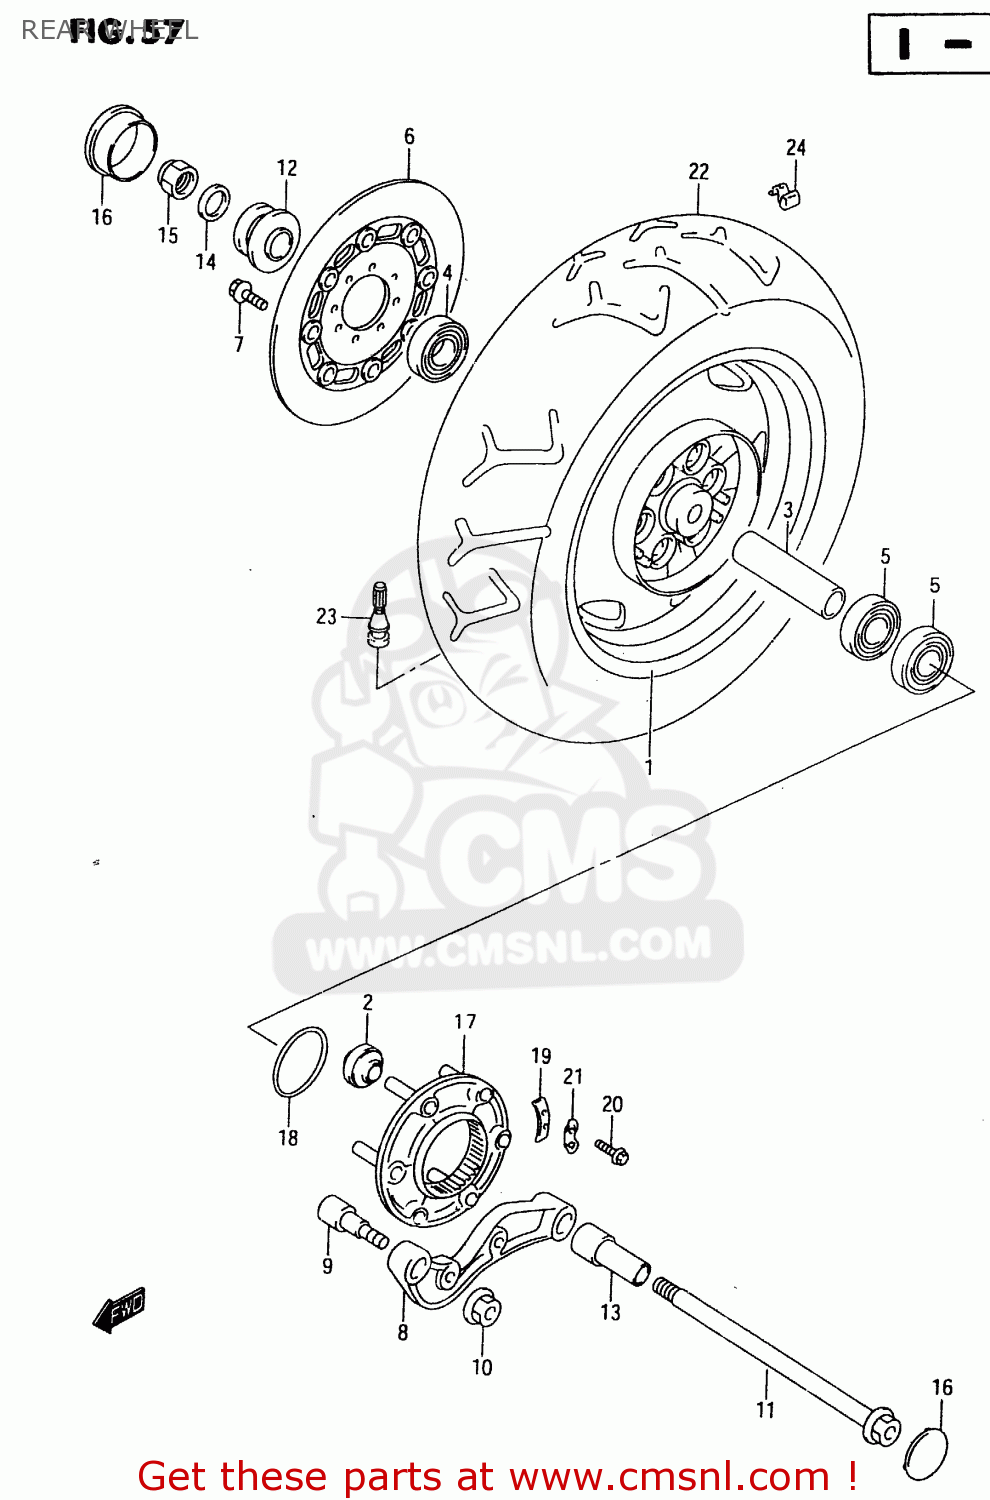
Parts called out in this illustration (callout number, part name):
1	WHEEL SET,RR(15XMT5.00)
2	BUSH
3	SPACER(20.8X27.2X124)
4	BEARING WHEEL REAR(20X47X14)
5	BEARING(20X47X14)
6	DISC,RR BRAKE
7	BOLT 8X33
8	BRACKET,REAR CALIPER
9	PIN,CALIPER BRACKET
10	NUT
11	AXLE,RR
12	SPACER,RR AXLE,R
13	SPACER,RR AXLE,L
14	WASHER
15	NUT
16	CAP,RR AXLE,L
17	JOINT ASSY,RR HUB DRIVEN
18	O RING(D:2.1,ID:65)
19	WASHER,THRUST(T:1.6)
20	BOLT(6X16)
21	WASHER
22	TIRE,RR(180/70-15M/C 76H)
23	VALVE ASSEMBLY,WHEEL,TR412
24	WEIGHT,BAL. 30
